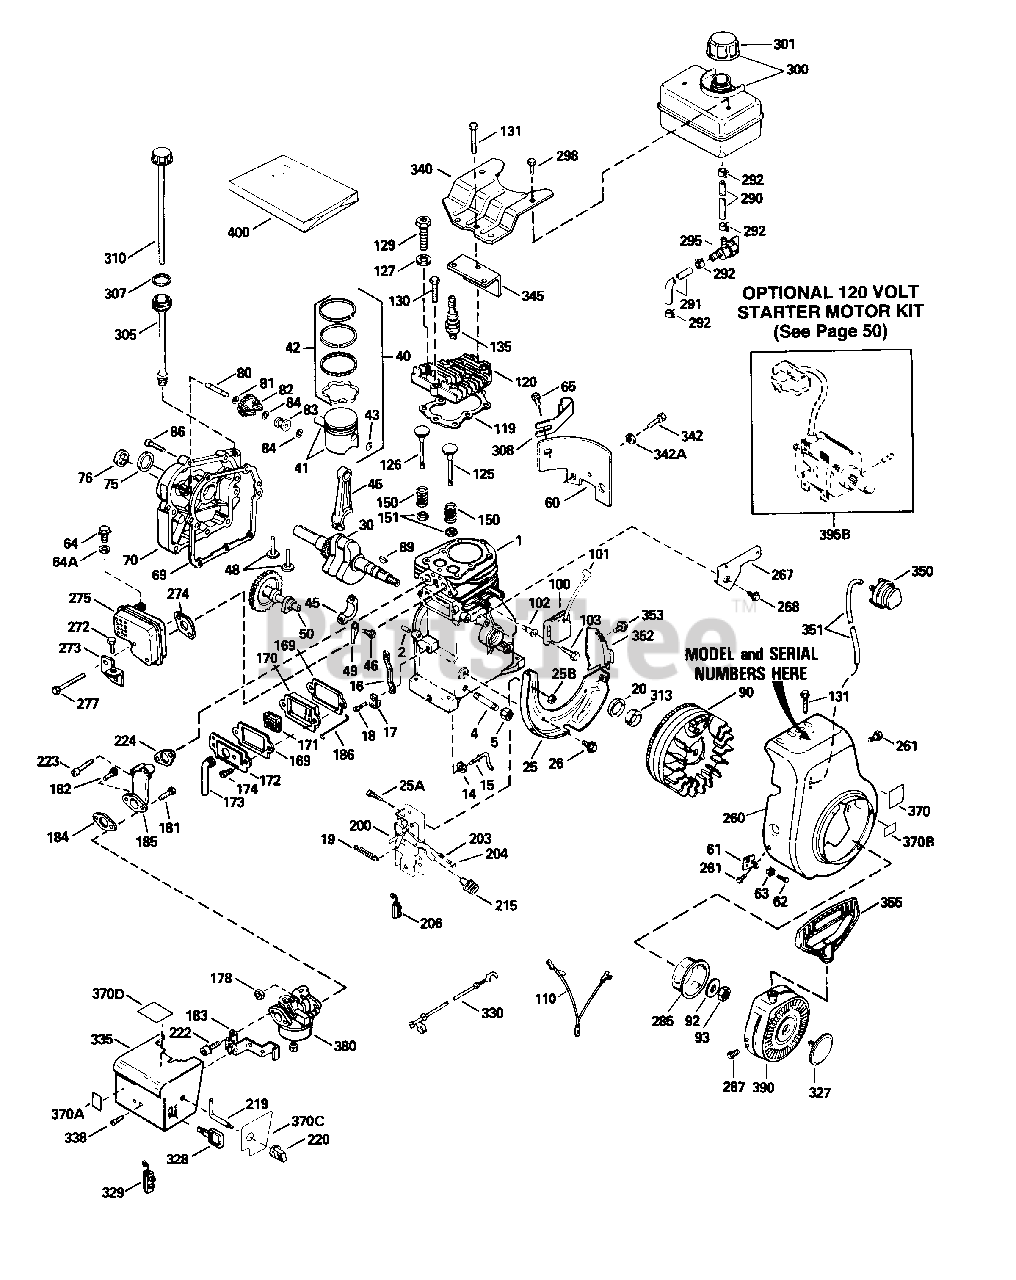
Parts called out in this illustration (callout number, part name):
1	Cylinder Ass'y.
2	Pin, Dowel
4	Nipple, Pipe
5	Cap, Oil Drain
14	Washer, Flat
15	Rod, Governor
16	Lever, Governor
17	Clamp, Governor Lever
18	Screw, Hex Washer Hd., 8-32 x 5/16
19	Spring, Extension
20	Seal, Oil
25	Baffle, Lower Housing
25A	Screw, Fil. Hd. Sems, 8-32 x 1/2
25B	Nut, Lock, 8-32
26	Screw, Hex Washer Hd. Durlok, 1/4-20 x 5/8
30	Crankshaft Ass'y.
40	Piston, Pin & Ring Ass'y. (Std.)
40	Piston, Pin & Ring Ass'y. (.010 Oversized)
40	Piston, Pin & Ring Ass'y. (.020 Oversize)
41	Piston & Pin Ass'y. (Std.)
41	Piston & Pin Ass'y. (.010 Oversize)
41	Piston & Pin Ass'y. (.020 Oversize)
42	Ring Set, Piston (Std.)
42	Ring Set, Piston (.010 Oversize)
42	Ring Set, Piston (.020 Oversize)
43	Ring, Piston Pin Retaining
45	Rod Ass'y., Connecting
46	Bolt, Connecting Rod
48	Lifter, Valve
49	Dipper, Oil
50	Camshaft (Compression Release)
60	Extension, Blower Housing
61	Bracket, Grommet Mounting
62	Screw, Pan Hd. Taptite, 8-32 x 3/8
63	Grommet, Plastic
64	Screw, Torx T-30 Hex Washer Hd. Sems, 1/4-20 x 1/2
64A	Washer, Flat
65	Screw, Hex Hd. Sems, 10-24 x 1/2
69	Gasket, Cylinder Cover
70	Cover, Cylinder
75	Seal, Oil
76	Seal, Camshaft
80	Shaft, Mechanical Governor
81	Washer, Flat
82	Gear, Governor
83	Spool, Governor
84	Ring, Retaining
86	Screw, Hex Hd. Sems, 1/4-20 x 1-1/4
89	Key, Flywheel
90	Flywheel (w/Ring Gear)
92	Washer, Belleville
93	Nut, Flywheel
100	Solid State Ass'y.
101	Cover, Spark Plug
102	Stud, Solid State Mounting
103	Screw, Torx T-15 Hex Washer Hd. Sems, 10-24 x 1
110	Wire, Ground
119	Gasket, Cylinder Head
120	Head, Cylinder
125	Valve, Exhaust (Std.)
125	Valve, Exhaust (1/32" Oversize)
126	Valve, Intake (Std.)
126	Valve, Intake (1/32" Oversize)
127	Washer, Flat
129	Screw, Special Hex Hd., 5/16-18 x 1-1/2
130	Screw, Hex Flange Hd., 5/16-18 x 1-1/2
131	Screw, Hex Flange Hd., 5/16-18 x 2
135	Spark Plug, Resistor
150	Spring, Valve
151	Cap, Valve Spring
169	Gasket, Valve Cover
170	Body, Valve Cover
171	Element, Valve Body
172	Cover, Breather
173	Tube, Breather
174	Screw, Hex Hd. Sems, 10-24 x 1/2
178	Nut & Lock Washer, 1/4-28
181	Screw, Hex Hd., 1/4-28 x 7/8
182	Screw, Hex Hd., 1/4-28 x 1-11/16
183	Bracket, Choke
184	Gasket, Carburetor
185	Pipe, Intake
186	Link, Governor to Throttle
200	Control Ass'y., Bracket
203	Spring, Compression
204	Screw, Fil. Hd., 5-40 x 7/16
206	Terminal Ass'y.
215	Knob, Speed Control
219	Rod, Choke
220	Knob, Choke Control
222	Screw, Fil. Hd. Sems, 10-32 x 1/2
223	Screw, Fil. Hd. Sems, 1/4-20 x 1-19/32
224	Gasket, Intake
260	Housing, Blower
261	Screw, Hex Hd. Sems, 1/4-28 x 7/16
267	Bracket, Hold Down
268	Screw, Hex Washer Hd. Self-Tap Sems, 10-24 x 9/16
272	Screw, Hex Hd. Sems, Taptite, 10-24 x 3/8
273	Bracket, Carburetor Cover
274	Gasket, Exhaust
275	Muffler
277	Screw, Fil. Hd. Sems, 1/4-20 x 2-1/2
285	Cup, Starter
287	Screw, Hex Washer Hd., 8-32 x 1/2
290	Line, Fuel
291	Line, Fuel
292	Clamp, Fuel Line
295	Valve, Shut-Off
298	Screw, Hex Washer Hd. Self-Tap Sems, 1/4-15 x 7/8
300	Tank Ass'y., Fuel
301	Cap, Fuel Tank
305	Tube Ass'y., Oil Fill
308	Clip, Oil Fill
313	Spacer, Flywheel Key
327	Plug, Starter
328	Key, Ignition
329	Terminal Ass'y.
330	Wire, Ground
335	Cover, Carburetor
338	Screw, Pan Hd. Sems, 8-32 x 5/16
340	Plate, Fuel Tank
342	Screw, Hex Hd. w/Belleville Washer, 1/4-20 x 1/2
342A	Washer, Flat
345	Baffle, Heat
350	Primer Ass'y.
351	Line, Primer
352	Extension, Baffle
353	Screw, Hex Wash. Hd., 8-32 x 1/2
355	Handle, Starter
370	Decal (5.0 H.P.)
370A	Decal, Instruction
370B	Decal, Primer
370C	Decal, Choke
370D	Decal, Warning
380	Carburetor
390	Starter, Rewind
395B	Electric Starter Kit
400	Gasket Set
